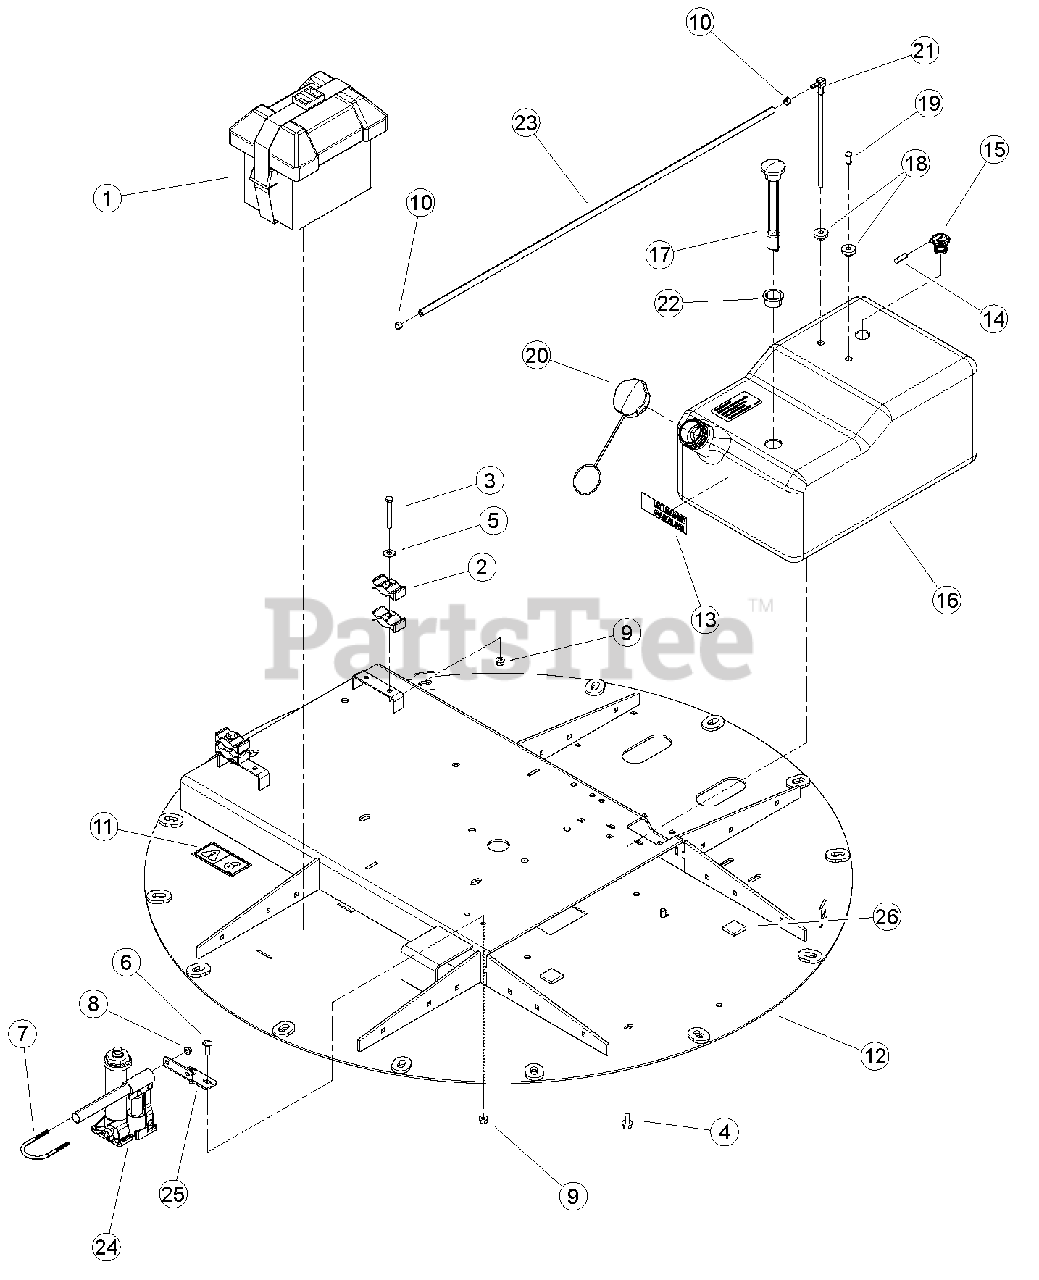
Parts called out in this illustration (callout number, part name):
1	BOX, SMALL BATTERY
2	CLAMP, PLASTIC HOSE
3	BOLT 5/16 X 2-1/2 G5 HX CAP ZP
4	BOLT, 3/8 X 3/4 FLANGE NC
5	WASHER, 5/16" FLAT ZP
6	BOLT, 5/16 X 1" GR5 CRG ZP
7	U-BOLT, 1/4 X 1-1/2 PIPE
8	NUT, 1/4-20 NYLOCK-FLANGE
9	NUT, 5/16-18 NYLOCK-FLANGE
10	CLAMP, 15/32 SPRING
11	DECAL, LOCK
12	WELDMENT, CHIPPER BASE
13	DECAL, UNLEADED GASOLINE
14	CAP, EPDM BLACK .223 ID X 1.0 LG X .06 WALL
15	VALVE, ROLL OVER
16	TANK, ROTOMOLDED FUEL
17	GAUGE, FUEL LEVEL KELCH 100
18	GROMMET, TANK FITTING
19	PLUG, TANK VENT
20	CAP, FUEL TANK VENTED
21	FITTING, TANK FUEL PICK-UP TUBE
22	GROMMET, KELCH 100 GAUGE
23	HOSE, 38" FUEL LINE
24	JACK, HYDRAULIC 2 TON
25	PLATE, JACK MOUNT
26	PAD, FOAM FUEL TANK DAMPER
